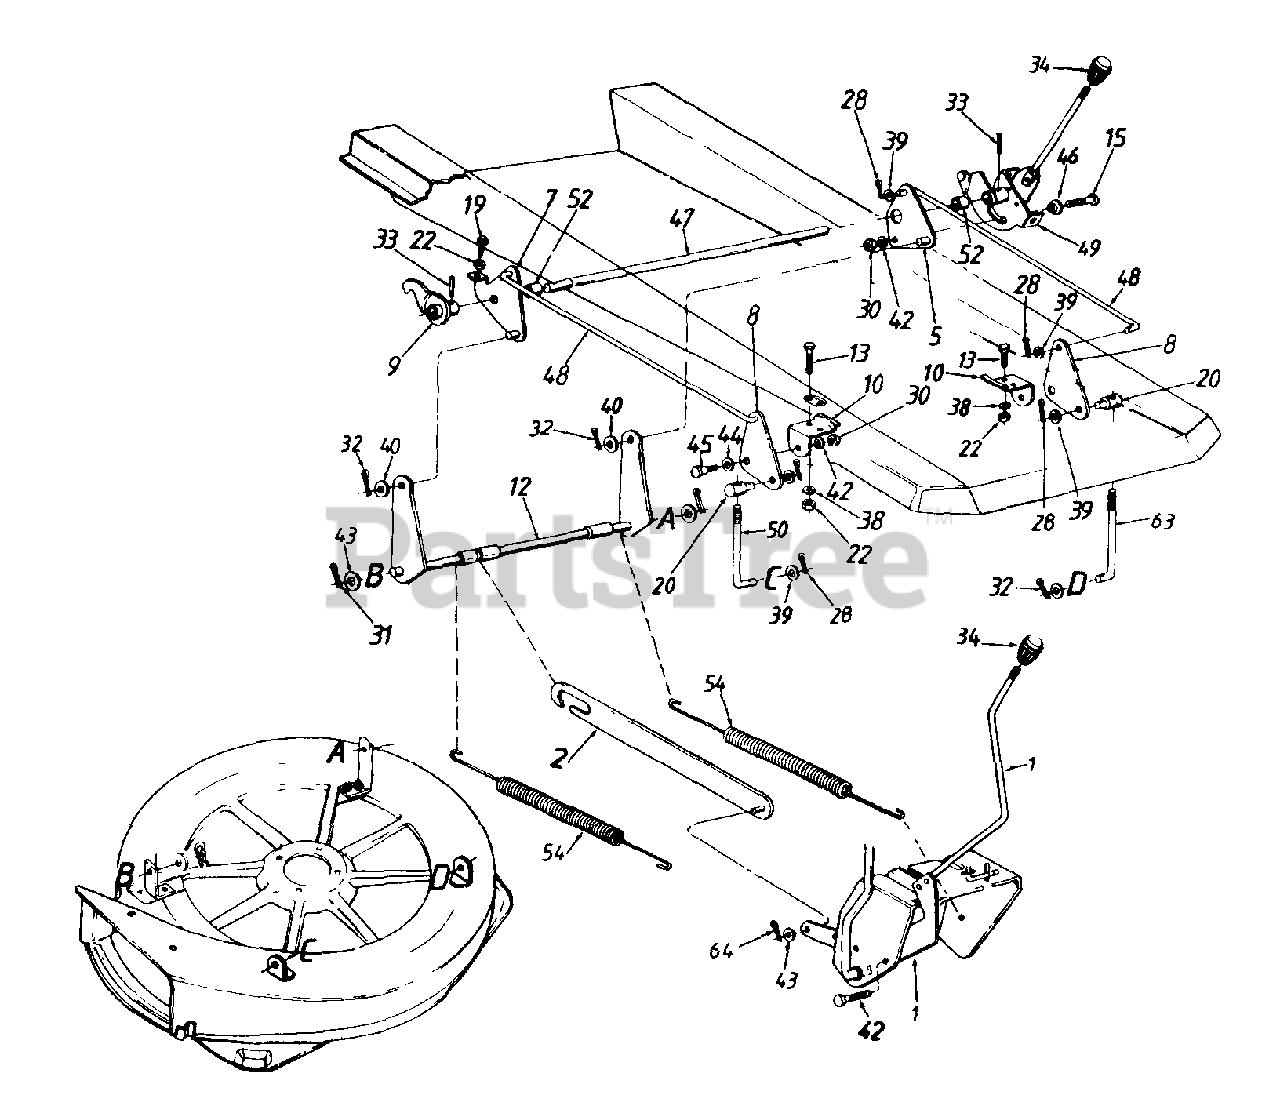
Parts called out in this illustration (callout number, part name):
7	Deck Lift Brkt. Ass'y.
8	Deck Lift Bracket
9	Deck Lift Float Brkt Ass'y.
10	Deck Lift Pivot Brkt.
15	Hex Bolt 3/8-16 x 1" Lg.
19	Hex Wash.-Tap Scr. 5/16-18 x 1.25" Lg.
20	Ferrule
22	Hex Nut 5/16-18 Thd.
28	Cotter Pin 3/32" Dia.
30	Hex Nut 3/8-16 Thd.
31	Internal Cot. Pin 1/2" Dia.
32	Int. Cot. Pins 3/8" Dia.
33	Spring Pin Spir 1/4" Dia
34	Knob
38	L-Wash 5/16" I.D.
39	Fl-Wash .385 I.D. x 62
40	Fl-Wash .635 I.D. x 1.12
42	L-Wash 3/8" I.D.
43	Fl-Wash .385 I.D. x .87 O.D.
44	Spring Washer .530 I.D.
45	Shld. Bolt .500" Dia. x 215"
46	Shld. Spacer .625" I.D.
47	Rear Hgt. Adj. Shaft
50	J-Bolt 3/8-24 x 5.25" Lg
52	Spacer 885 I.D
54	Ext. Spring 13.25" Lg
63	J-Bolt 3/8-24 x 5.4" Lg
64	Cotter Pin 1/8" Dia.
